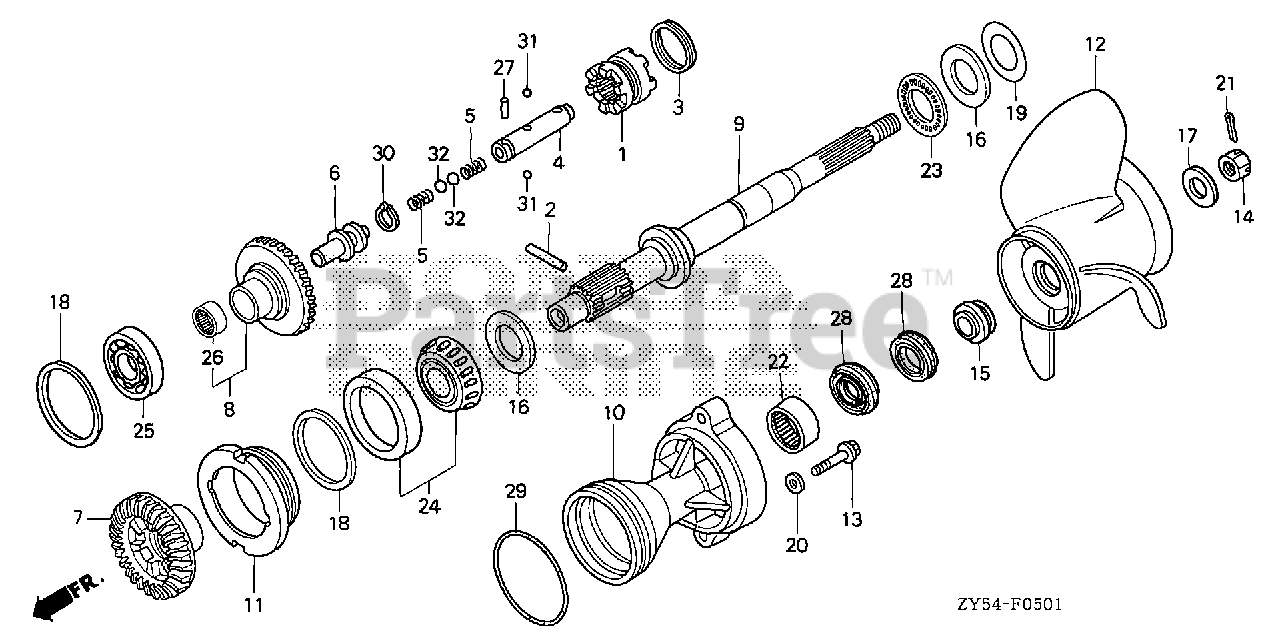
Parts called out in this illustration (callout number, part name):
1	SHIFTER, CLUTCH
2	PIN, SHIFTER (8X47)
3	RING, CROSS PIN
4	SLIDER, SHIFT
5	SPRING, SHIFT
6	PLATE, SHIFT
7	GEAR, BEVEL (FORWARD 30T) (COUNTER ROTATION)
8	GEAR, BEVEL (RVS. 30T) (COUNTER ROTATION)
9	SHAFT, PROPELLER (COUNTER ROTATION)
10	HOLDER, PROPELLER SHAFT *NH282MU* (OYSTER SILVER METALLIC-U)
11	HOLDER, BEARING (COUNTER ROTATION)
12	PROPELLER, THREE-BLADE (14-1/2X15) (C/R)
12	PROPELLER, THREE-BLADE (14-1/4X17) (C/R)
12	PROPELLER, THREE-BLADE (14X19) (C/R)
12	PROPELLER, THREE-BLADE (14X21) (C/R)
12	PROPELLER, THREE-BLADE (14-1/2X23) (C/R)
13	BOLT, FLANGE (10X40)
14	NUT, CASTLE (18MM)
15	WASHER, PROPELLER THRUST
16	WASHER, THRUST BEARING
17	WASHER, PROPELLER
18	SHIM A, BEVEL (0.10)
18	SHIM B, BEVEL (0.15)
18	SHIM C, BEVEL (0.30)
18	SHIM D, BEVEL (0.50)
19	SHIM A, THRUST (0.10)
19	SHIM B, THRUST (0.15)
19	SHIM C, THRUST (0.30)
19	SHIM D, THRUST (0.50)
20	WASHER, PLAIN (10MM)
21	PIN, SPLIT (4.0)
22	BEARING, NEEDLE (30X37X26)
23	BEARING, THRUST (F)
24	BEARING, TAPER (50X90X28)
25	BEARING, RADIAL BALL (50X90X20)
26	BEARING, NEEDLE (25X32X26)
27	ROLLER (3X12.8)
28	SEAL, WATER (30X45X7)
29	O-RING (105X3.1)
30	CIRCLIP, OUTER (14MM)
31	BALL, STEEL (#7) (7/32)
32	BALL, STEEL (#9) (9/32)
